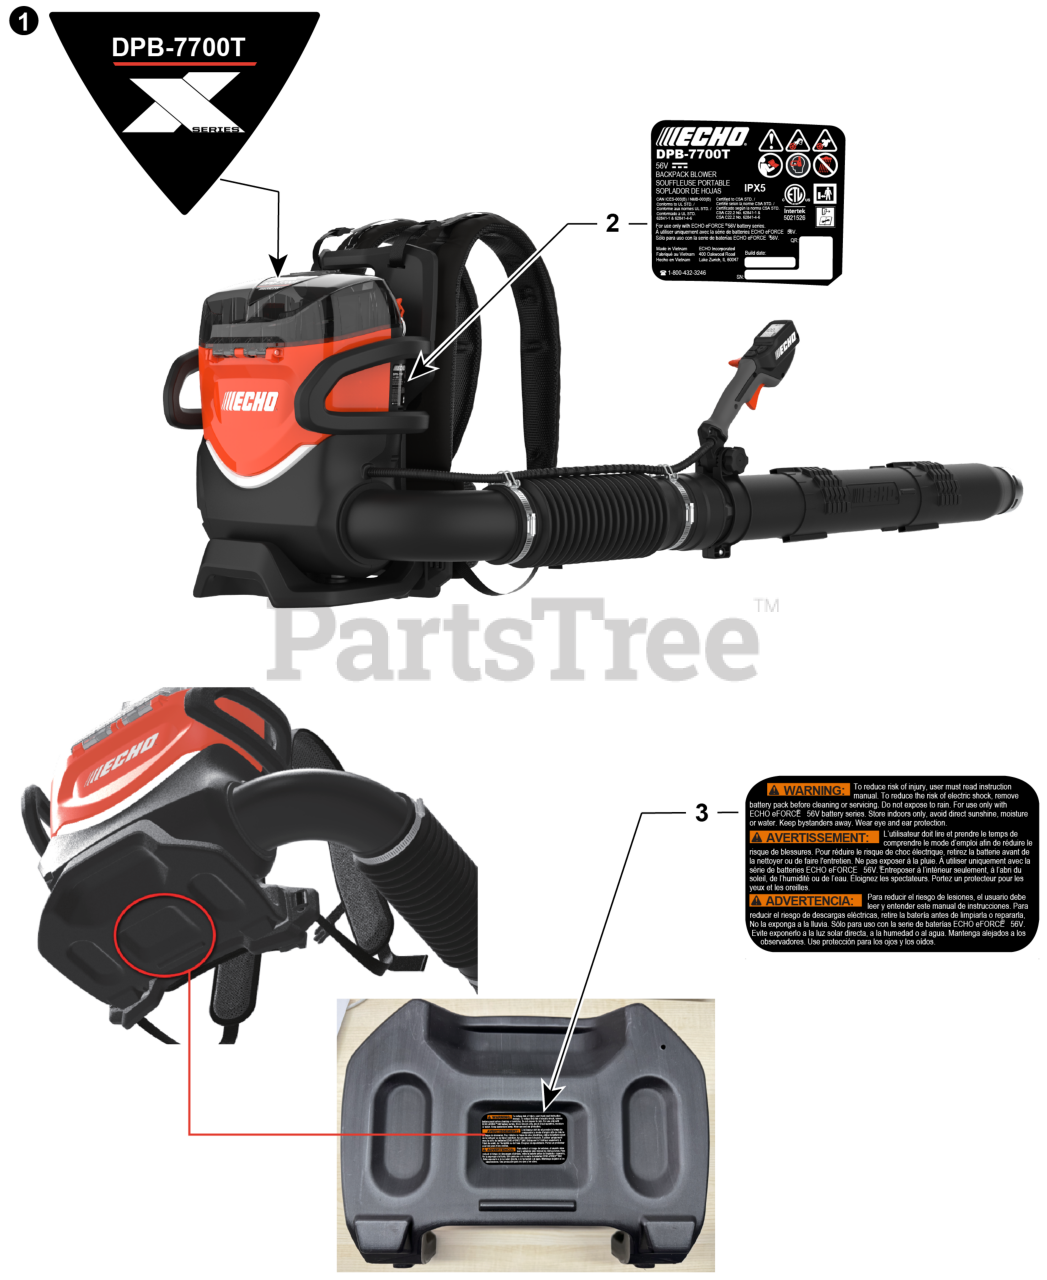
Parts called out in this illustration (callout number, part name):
1	LABEL, MODEL
2	LABEL, NAMEPLATE
3	LABEL, WARNING
